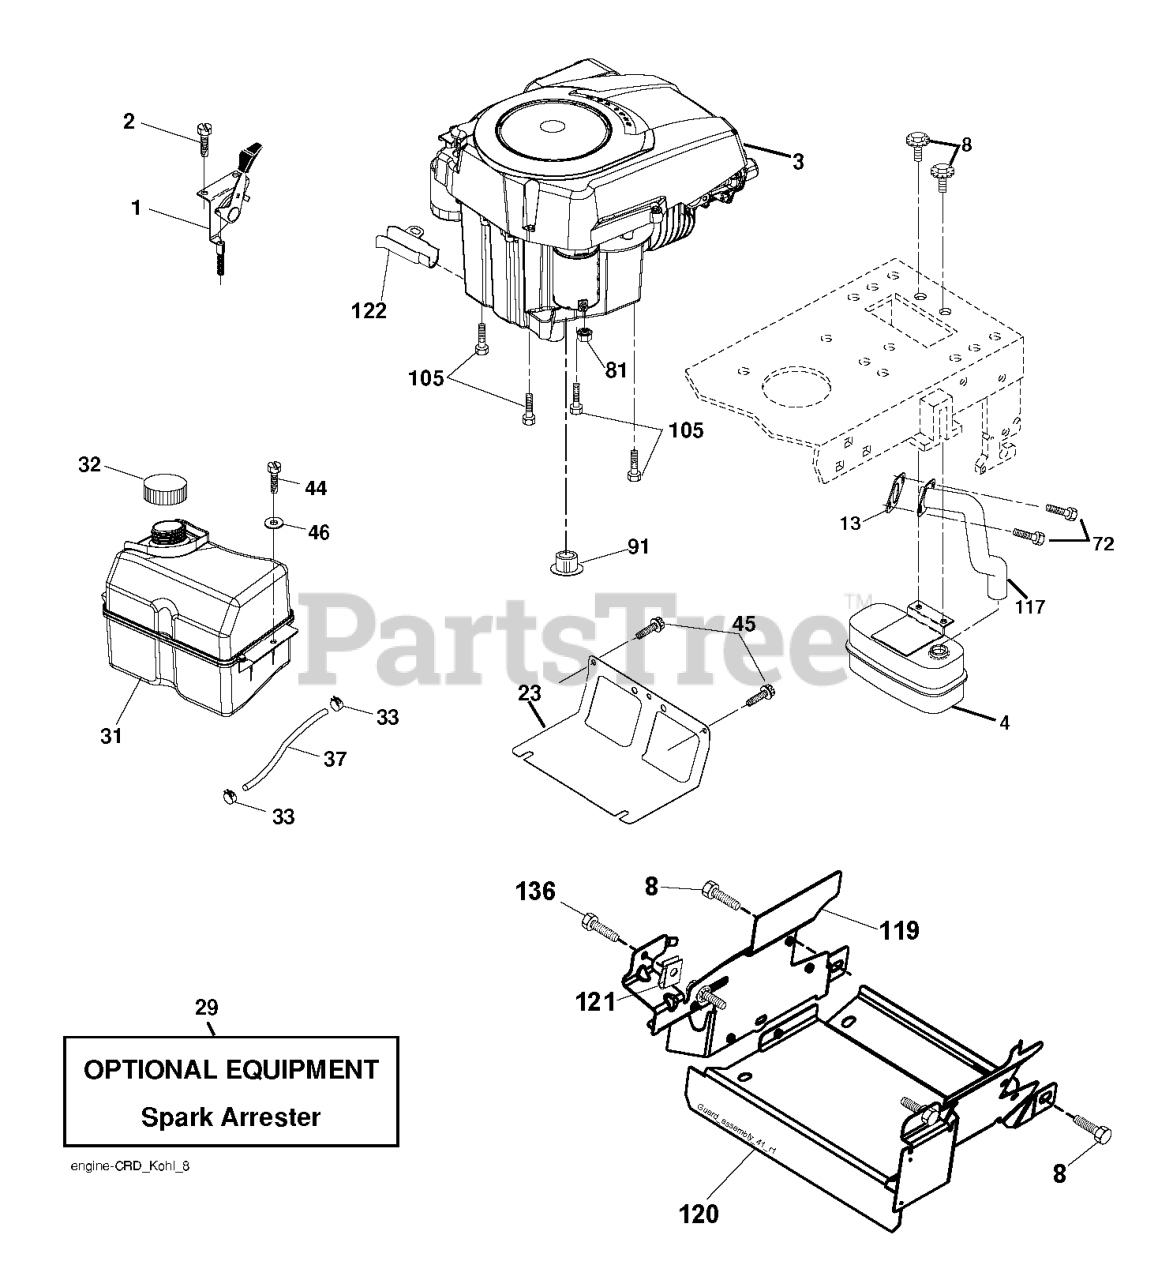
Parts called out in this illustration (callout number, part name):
1	CONTROL.TH/CK.C.
2	SCREW.#10 X 0.750.BOS
4	MUFFLER.SINGLE.CYL.KOHL/B&S
8	BOLT.5/16-18UNCX3/4 W/SEMS.BLK
13	GASKET.EXHAUST.KOHLER
23	SHIELD.BROWNING.DBR.GUARD
29	KIT.SPARK ARRESTOR 794945 B&S
31	RP TANK FUEL FRT 1.5 GAL
32	CAP ASM.FUEL.2.25"FR.
33	HOSE CLAMP
37	LINE.FUEL.20
44	SCREW HEXWSHR 1/4-20X3/4
45	SCREW, 3/8-16X3/4
72	SCREW.SOCKET HD.5/16-1
81	NUT
91	BUSHING.1.375OD
105	SCREW 3/8-16X1
117	RP.TUBE.EXHAUST.KOHL.COURAGE
119	LENKRAD
120	GUARD 532199767
122	EXTENSION DRAIN OIL
136	SCREW.1/4-20X5/8
